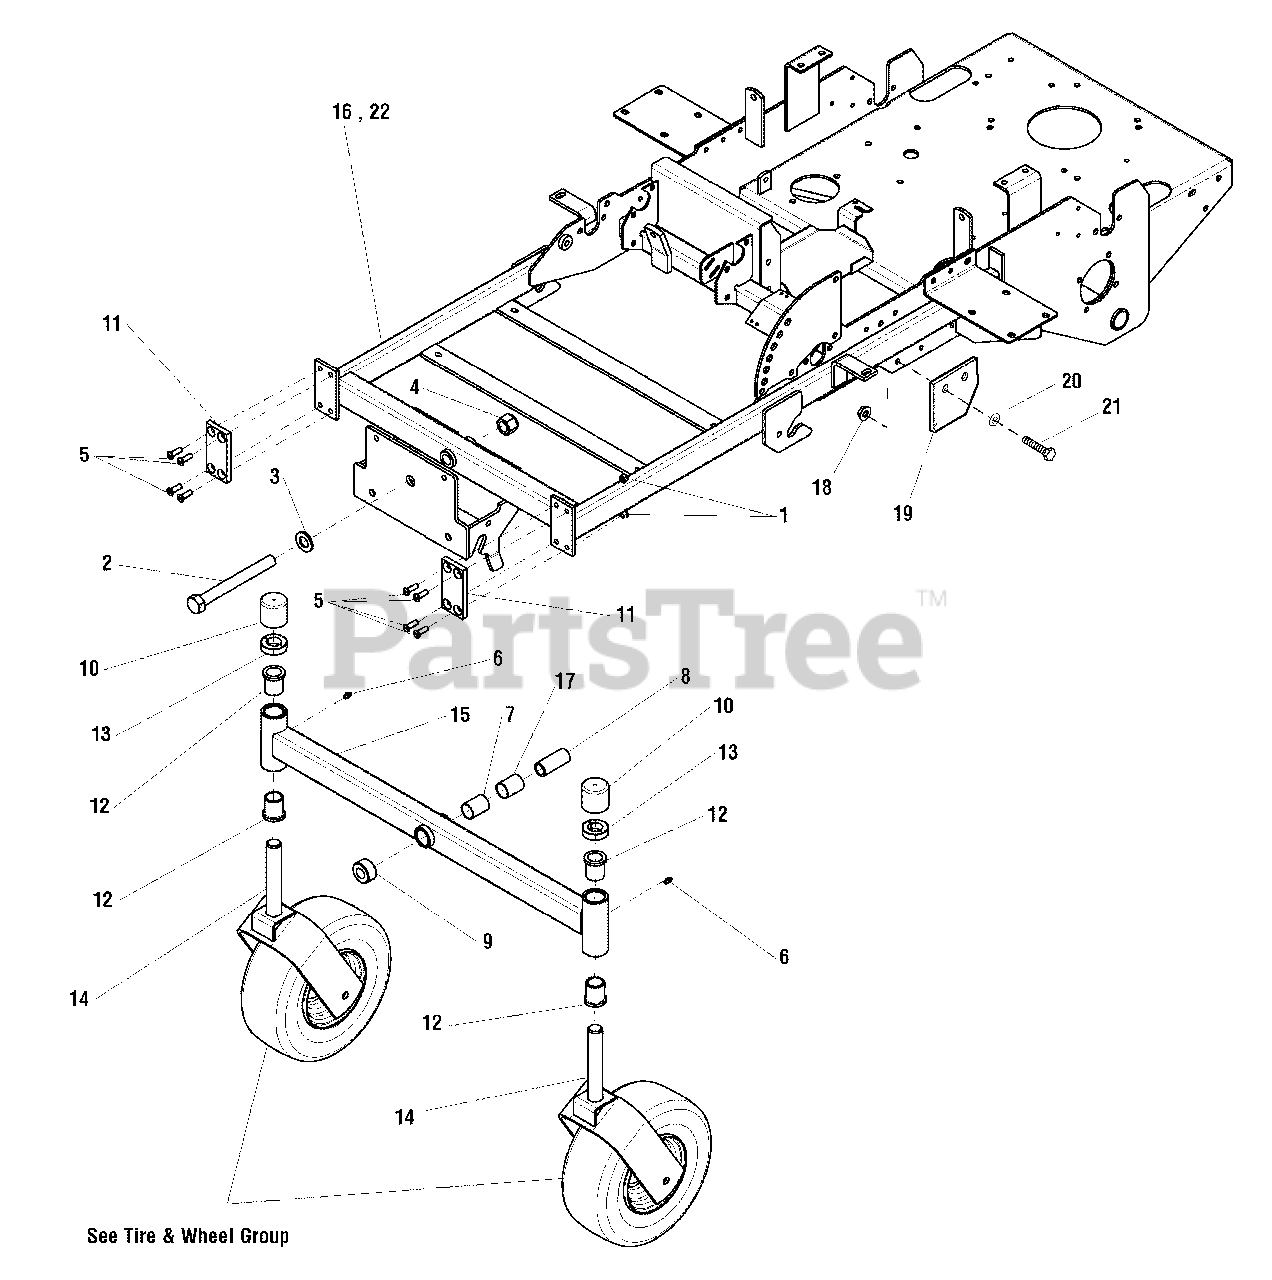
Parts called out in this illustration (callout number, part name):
1	NUT 5/16-18 HEX NYLON LOCK
2	3/4-16 X 7" GD 8 BOLT TZ
3	WASHER, 3/4" SAE
4	NUT, 3/4-16 HEX NYLON LOCK
5	SCREW 5/16-18 X 1 FLAT HD SC
6	GREASE FITTING, 1/4-28 STR
7	PIVOT BEARING,1.00" X 1.125" OD X 1.50"
8	SPACER, .75 X 1.00 X 2.38
9	SPACER, .75 X 1.50 X .785
10	CAP, VINYL 1.687 X 1-1/2
11	PLATE, FRICTION REDUCER
12	BUSHING, FLANGE
13	COLLAR, 1" SPLIT
14	WELD, CASTER YOKE
15	WELD, PIVOTING FRONT END
16	WELD, MAIN FRAME, SNAPPER ZT
17	BEARING, PIVOT, 1.00 X 1.25 X .50
18	NUT, 5/16-18 HEX NYLOCK FLANGE
19	PLATE, DECK STOP - SNAPPER RED
20	WASHER, 5/16" SAE
21	BOLT, 5/16-18 X 3/4 GD5
22	WELD, MAIN FRAME, SNAPPER 400Z
